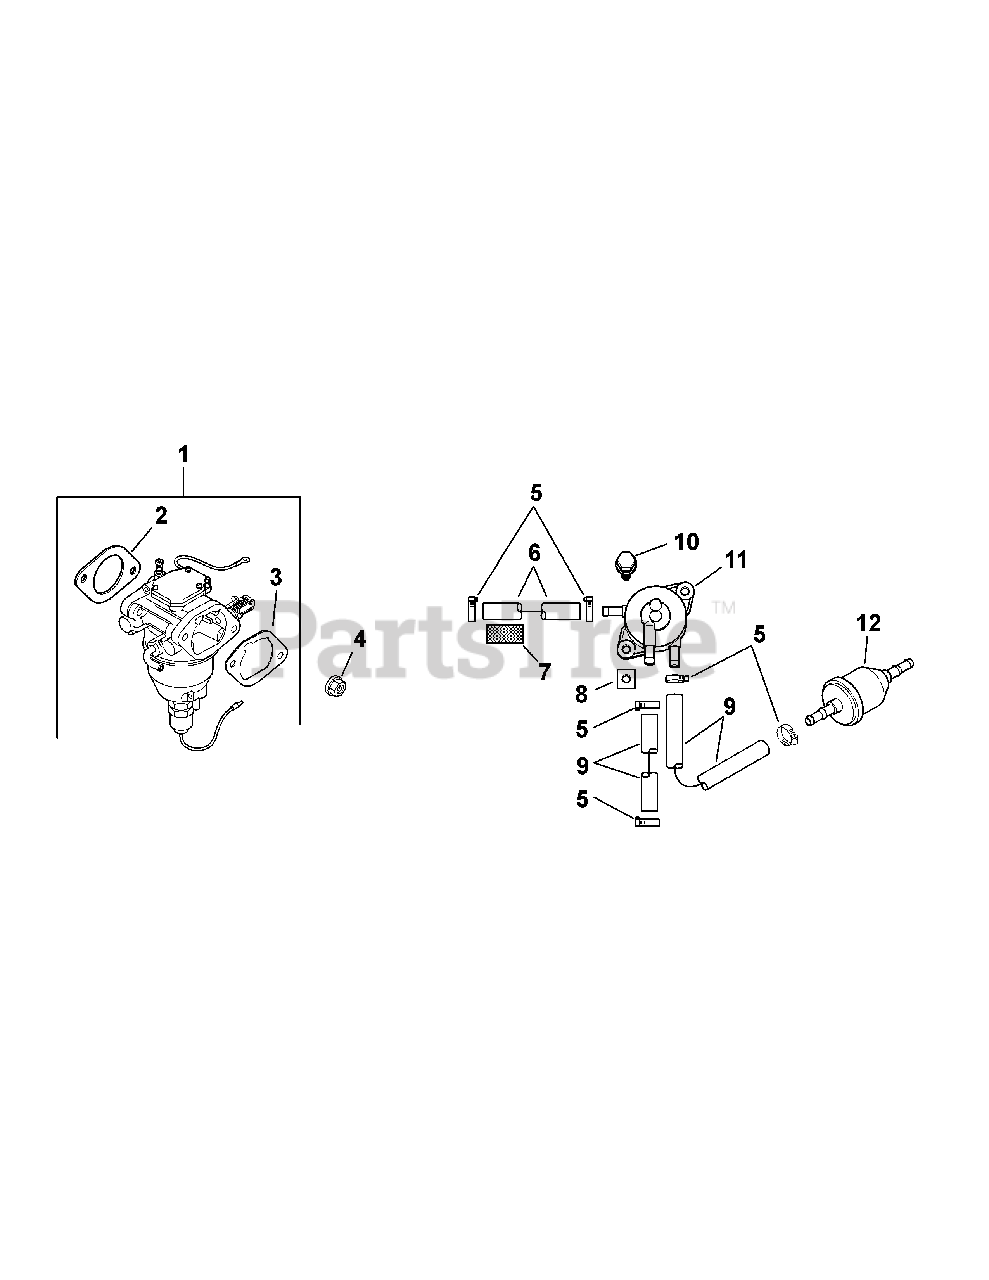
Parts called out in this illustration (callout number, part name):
1	Kit, Carburetor W/Gaskets (Includes 2,3)
2	Gasket, Carburetor
3	Gasket, Air Cleaner Base
4	Nut, Flg M6x1.0
6	Line, Flex 11" Pump-Pulse (Air Only)
7	Sleeve, Insulating 14"
9	Line, Fuel
10	Screw, Tap M6x1.7x18
